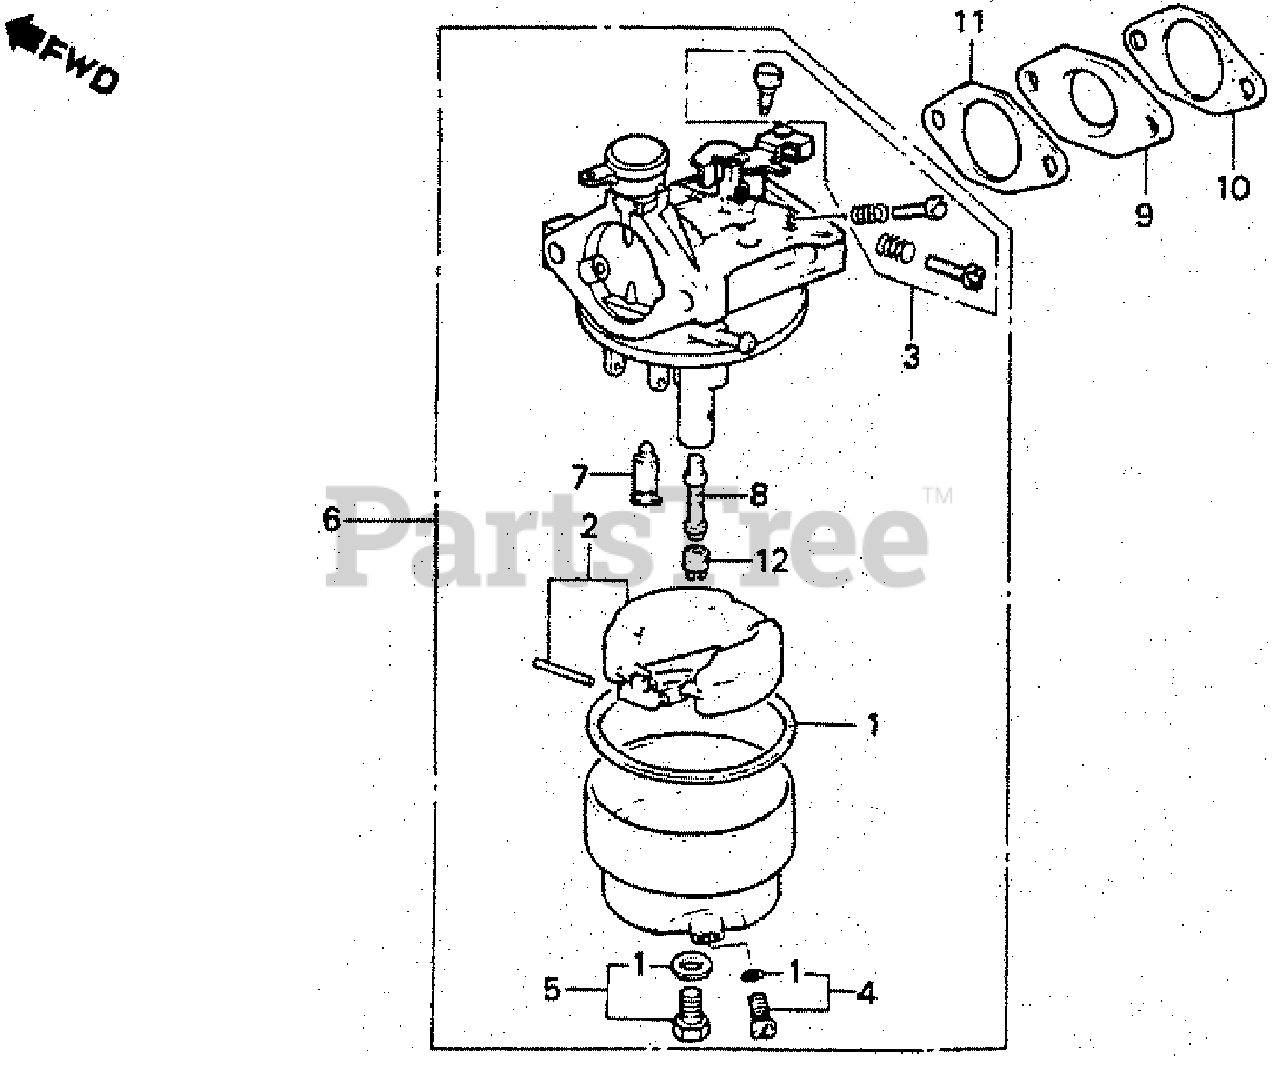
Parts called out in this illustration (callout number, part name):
1	GASKET SET
3	SCREW SET A
4	SCREW SET, DRAIN
5	SCREW SET B
6	CARBURETOR ASSY.
7	VALVE, FLOAT
8	NOZZLE, MAIN
9	INSULATOR, CARBURETOR
10	GASKET, INSULATOR
11	GASKET, CARBURETOR
12	JET, MAIN (#72)
